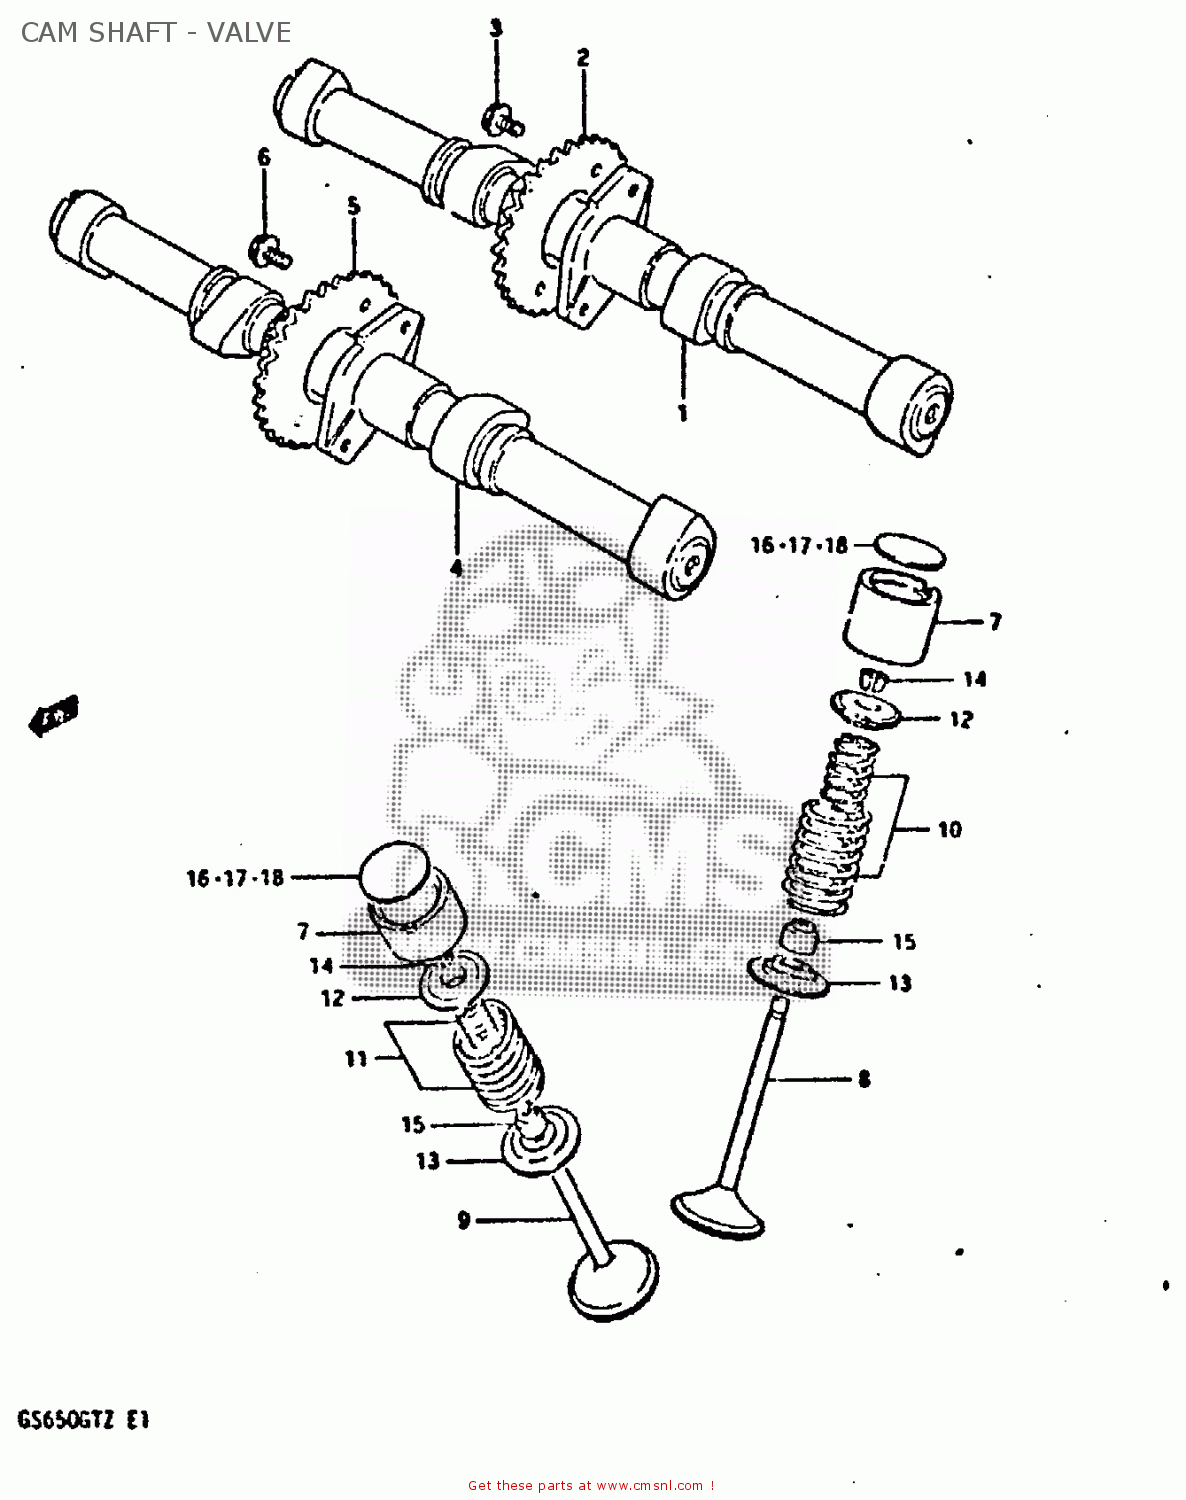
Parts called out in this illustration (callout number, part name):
1	CAMSHAFT,INTAKE
2	SPROCKET,INTAKE CAMSHAFT
3	BOLT(7X11)
4	CAMSHAFT,EXHAUST
5	SPROCKET,EXHAUST CAMSHAFT
6	BOLT(7X11)
7	TAPPET
8	VALVE,INTAKE
9	VALVE,EXHAUST
10	SHIM,TAPPET
11	SHIM,TAPPET
12	RETAINER,VALVE SPRING
13	SEAT,VALVE SPRING
14	COTTER VALVE
15	SEAL,OIL(7X14.4X9)
16	SHIM,TAPPET
17	SHIM,TAPPET
18	SHIM,TAPPET
